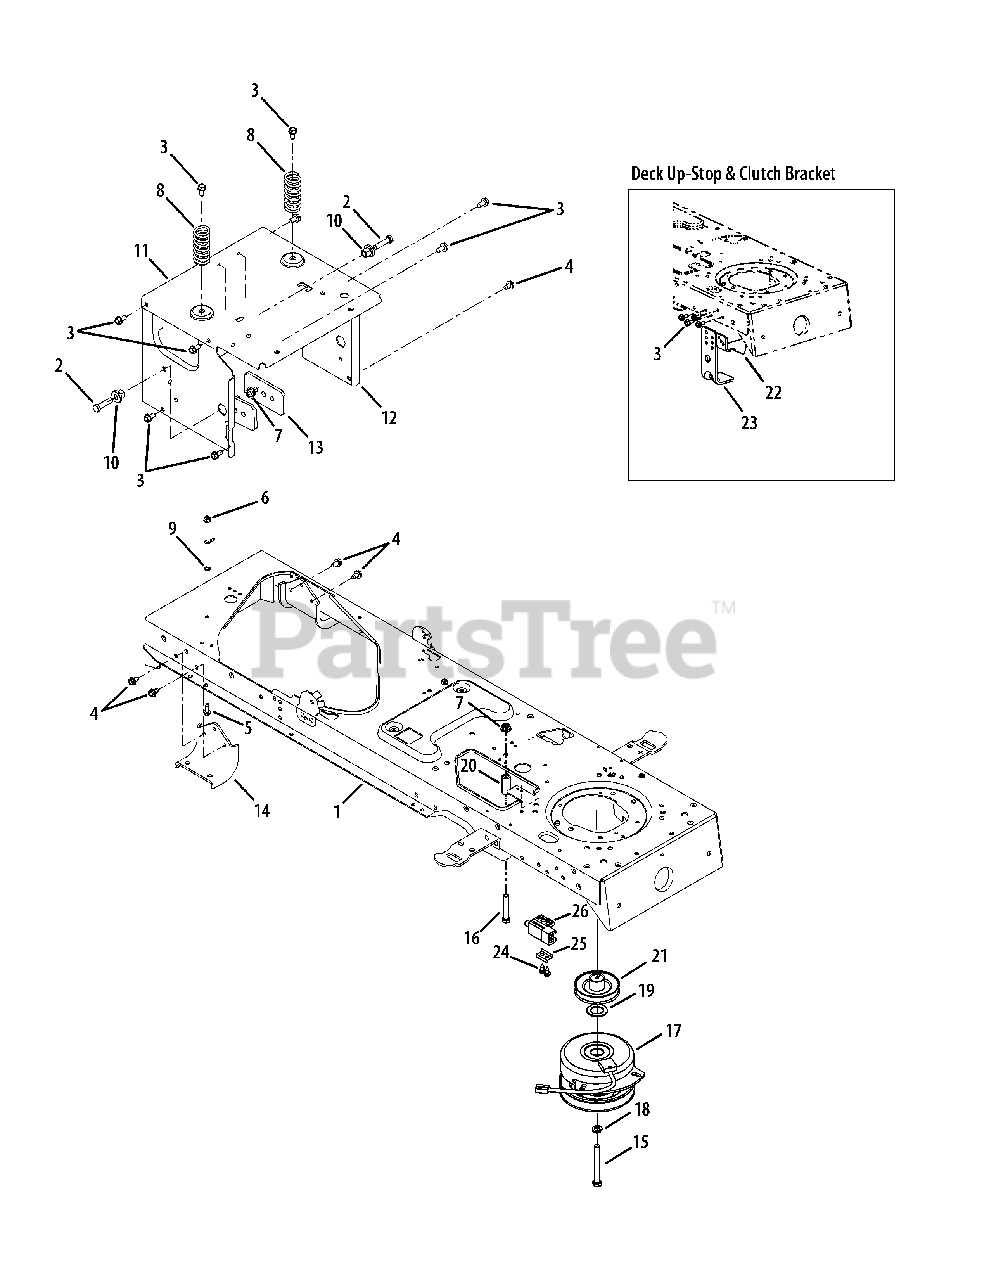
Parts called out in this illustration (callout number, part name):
1	Frame Assembly, Lower
2	Hex Screw 3/8-16 x 1.25
3	Screw, Self-tapping, 5/16-18, 0.75
4	Screw, Hex Wash. Tapp, 5/16-18 x .5
5	Screw, Hex Wash., 1/4-20 x 0.750
6	Nut, Nylon Lock, 1/4-20
7	Nut, Nylon Lock, 3/8-16
8	Spring, Compression, 1.71 x .3735 x 2.38
9	Washer, Lock, Ext. 1/4
10	Shoulder Spacer
11	Bracket, Frame, Seat
13	Support Plate
14	Axle Bracket
15	Screw, Hex Cap , 7/16-20 x 3.5 GR5
16	Screw, 3/8-16 x 2.25 GR5
17	Clutch, PTO
18	Washer, Lock, 7/16, Regular Duty
19	Washer, Flat, 1.031 x 1.62 x .095
20	Spacer, 3/8 x 1.54
21	Electric PTO Engine Pulley
22	Clutch Bracket
23	Deck Up-stop Bracket
24	Screw, #10 - 16, x .500
25	Switch Mounting Plate
26	Interlock Switch
